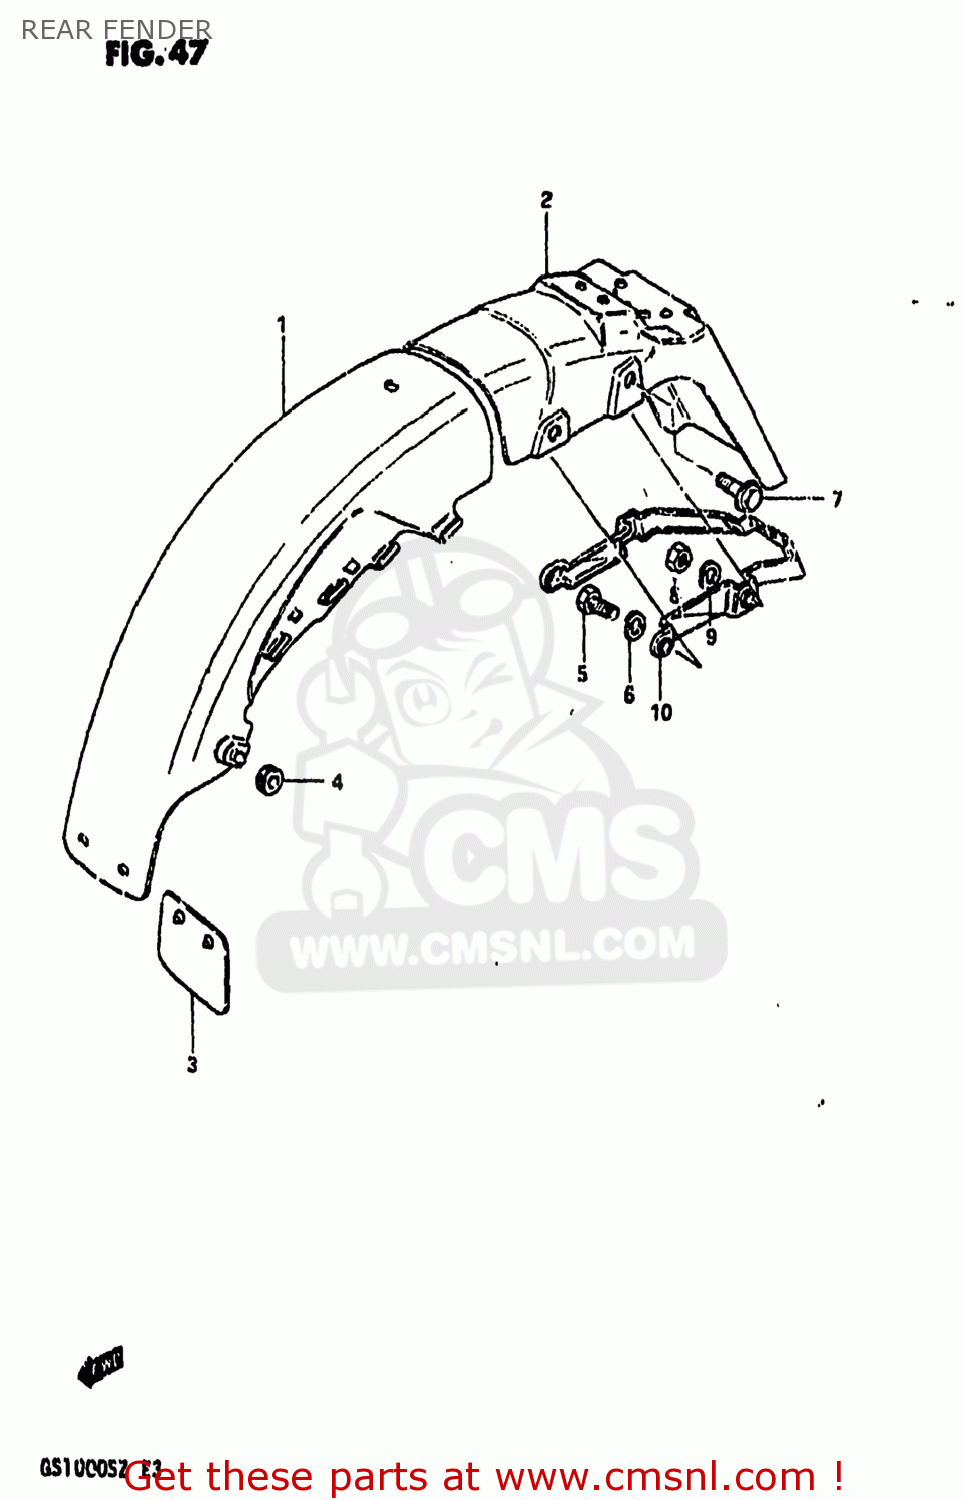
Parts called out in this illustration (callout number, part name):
1	FENDER,REAR
2	BODY,RR FENDER RR
3	GUIDE,RR FENDER MUD
4	CUSHION
5	BOLT, UPPER
6	LOCK WASHER
7	BOLT
8	NUT
9	LOCK WASHER
10	REINFORCEMENT,RR FENDER
